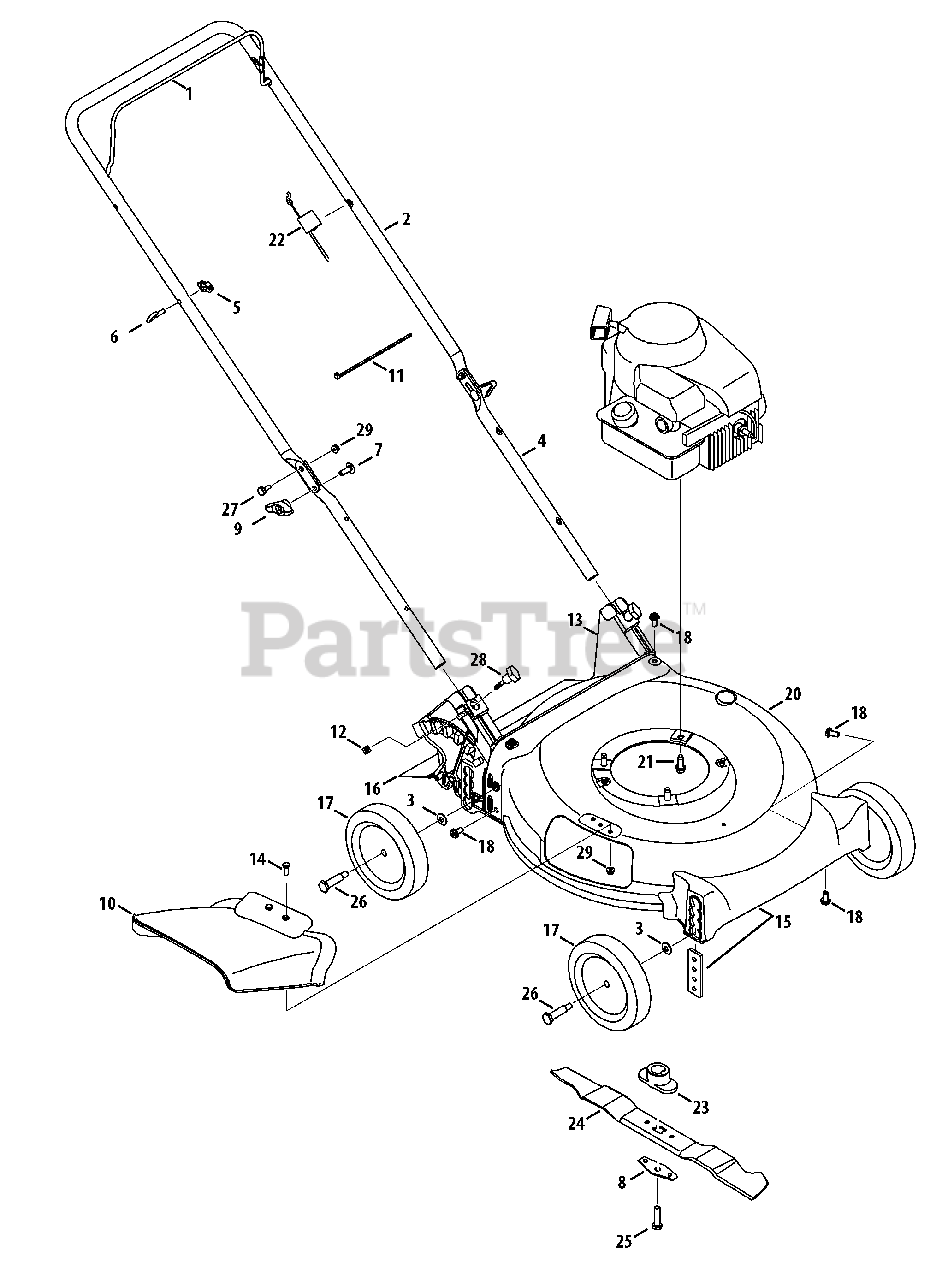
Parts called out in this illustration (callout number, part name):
1	Blade Control Handle - Black
2	Upper Handle - Black (adjustable)
3	Cupped Washer
4	Lower Handle
5	Knob 1/4-20
6	Rope Guide Bolt
7	Carriage Bolt 5/16-18
8	Blade Bell Support
9	Wing Knob 5/16-18 Black
10	Chute Deflector
11	Cable Tie
12	Sq. Nut 1/4-20
13	Rear Baffle Ass’y
14	Hex. Hd. Cap Scr. 1/4-20 x .75
15	Front Axle Cover
16	Trailing Shield 4.54 x 17.37
17	Wheel Ass’y 7 x 1.5 Diamond Star
18	Hex Hd. Cap Scr. 5/16-14 x .75
20	21" Deck Ass’y
21	Hex Wash HD Tap Scr 3/8-16 x 1.0
22	Control Cable, 148 cc B&S
23	Blade Adapter
24	21" Mulching Blade
25	Hex Bolt 3/8-24 x 1.5" Lg. (Gr 8)
26	Shoulder Screw .498 x 1.6
27	Shoulder Screw .375 x .126 x 1/4-20
28	Knob 1/4-20 x 1.725 Black
29	Flanged Lock Nut 1/4-20 Gr. F Nylon
